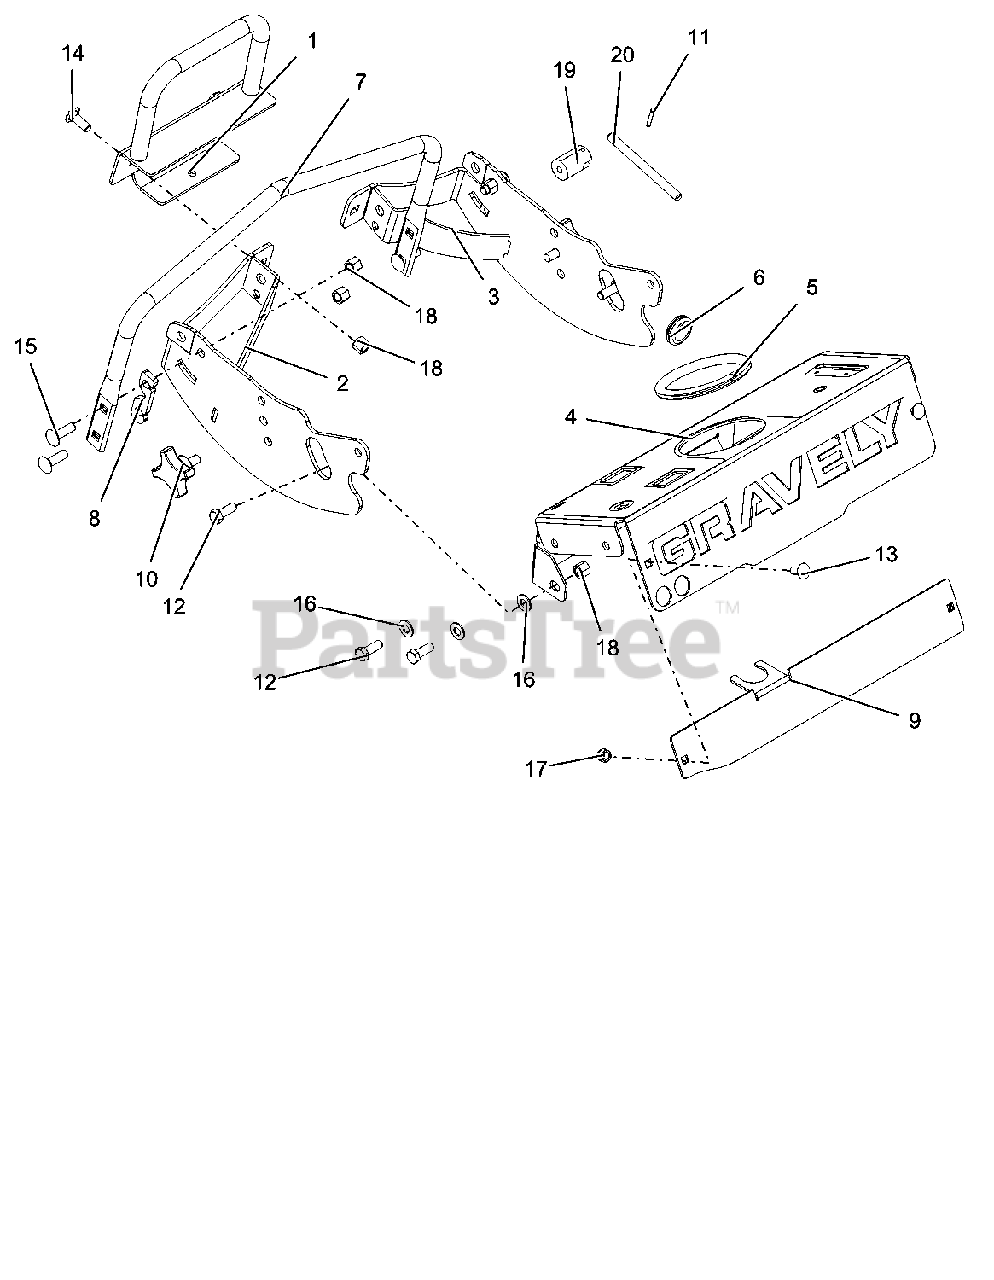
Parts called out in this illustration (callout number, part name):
1	WLDMT, REVERSE BAR (RED)
2	WLDMT, RH CONTROL MOUNT-RED
3	WLDMT, LH CONTROL MOUNT-RED
4	ASM, PS CONSOLE W/DECAL 36GRV
5	TRIM, RUBBER DEGE 12"
6	GROMMET:RUB:.88IDx1.38ODX.14GR
7	SUPPORT, HANDLE-RED
8	SHIM, BAR 5 DEG SPEED-RED
9	BRACKET, REMOTE ROV HYDRO-BLACK
10	KNOB, 3/8-16 x .75
11	PIN, SPRING
12	BLT-HEX .38-16X1.00 GR5 YWZC
13	BLT-RDHDSQNK .31-18X.75 G5 YWZC
14	BLT-RDHDSQNK .38-16X1.00 G5 YWZC
15	BLT-RDHDSQNK .38-16X1.25 G5 YWZC
16	WSHR-FL-STL.406X.812X.065 YWZ
17	NUT-LK-NYL .312-18 YWZC
18	NUT-LK-NYL .38-16 YWZC
19	BASE, LOCK LEVER Y
20	LEVER, LOCK Y
